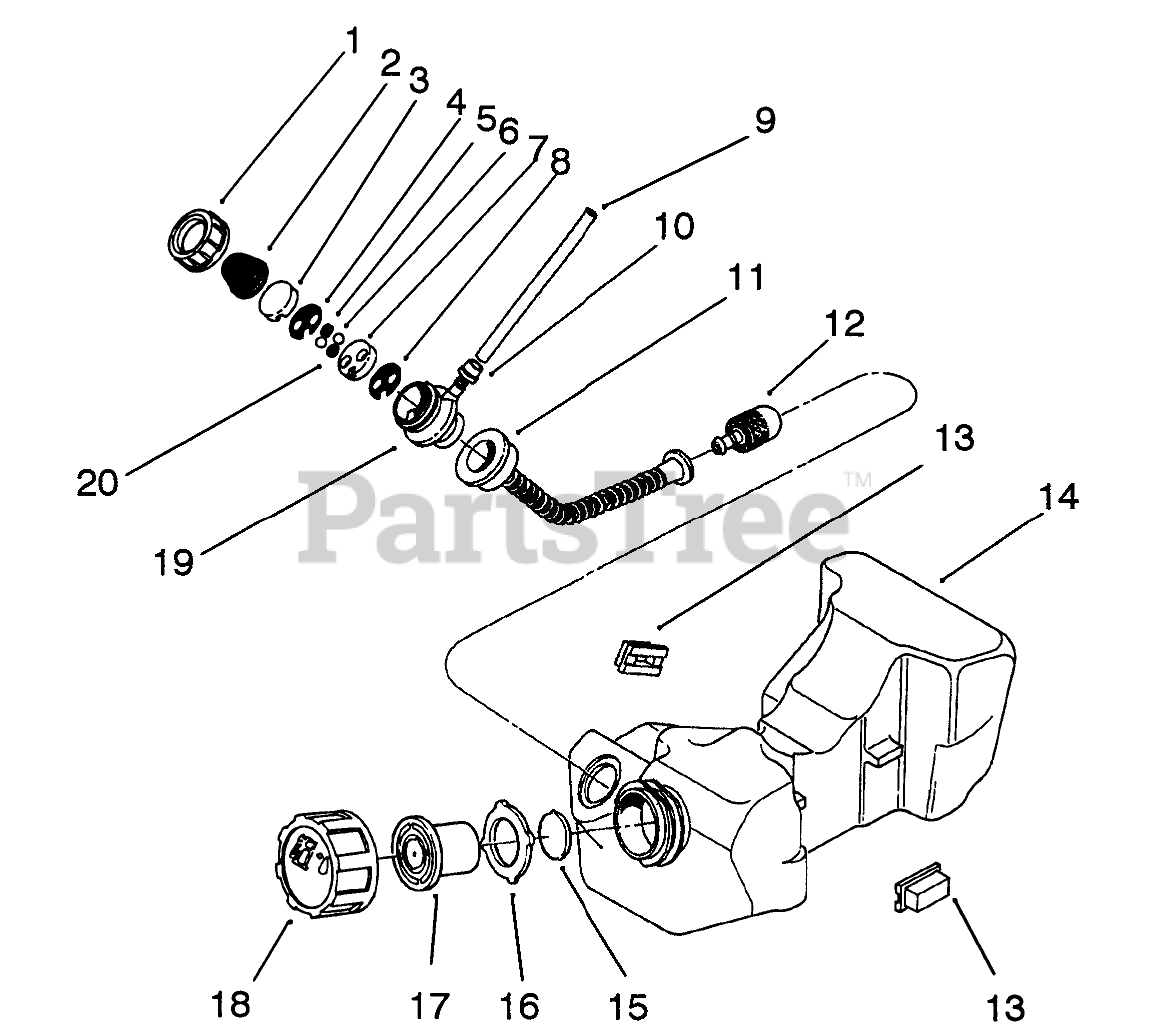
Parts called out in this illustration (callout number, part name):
1	PUMP CAP
3	SEAT VALVE
4	GASKET
5	SPONGE
7	SEAT VALVE
8	GASKET
9	Tube-Fuel
11	SUCTION HOSE
12	FUEL FILTER
14	Fuel Tank Assembly (Incl. Ref. #11, 12 15-18 & 19)
16	PACKING
17	BREATHER VALVE
18	FUEL TANK CAP
19	Pump Priming Assembly (Incl. Ref. #1-8 & 20)
20	Cushion Ball
